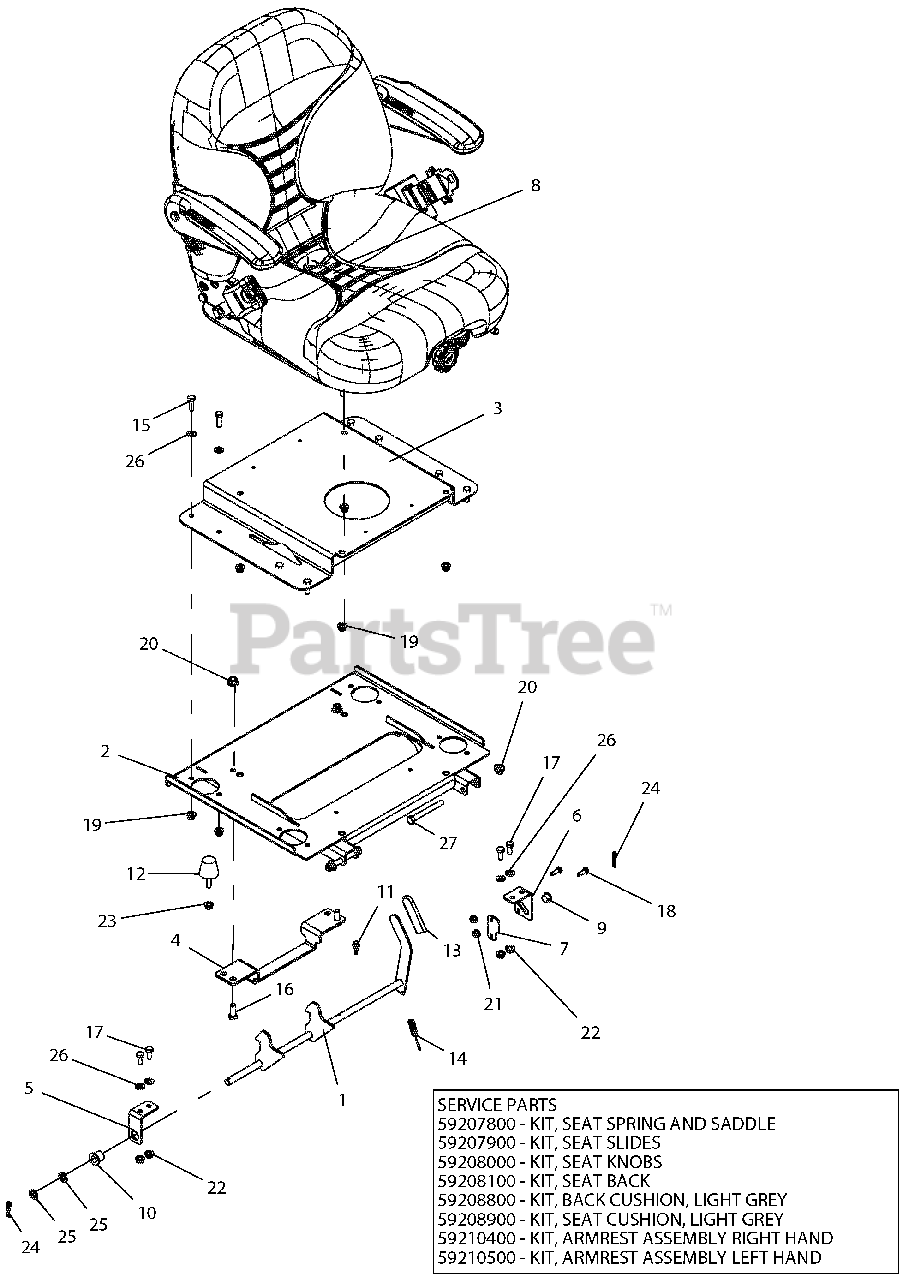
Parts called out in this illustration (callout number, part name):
1	WMT, SEAT LATCH
2	WLDMT, SEAT ISO MOUNTING-RED
3	WLDMT, SEAT BASE MOUNTING-RED
4	BRKT, SEAT LATCH-BLACK
5	MOUNT, SEAT LATCH - RH
6	MOUNT, SEAT LATCH - LH
7	RETAINER-SEAT LATCH
8	SEAT, SUSPENSION W/SEAT BELT, LT GRAY
9	BUSHING, POLYLINER - .50 SPLIT
10	BSHG, FLANGE .515 X .750 X .745 X 1.00 NYLON
11	CABLE TIE W/ TREE (.25 HOLE)
12	BUMPER, STUD MOUNTED CONE SHAPED
13	GRIP-VINYL-YELLOW .125 x 1.0 x 3.0
14	SPRG, EXTENSION
15	BLT-HEX .31-18X1.00 GR5 YWZC
16	BLT-HEX .38-16X1.00 GR5 YWZC
17	BLT-HEX .31-18X.75 GR5 YWZC
18	BLT-HEX .25-20X.75 GR5 YWZC
19	NUT-LK-NYL-FLG .31-18 YWZC
20	NUT-LK-NYL-FLG .38-16 YWZC
21	NUT, LK-TOP-FLG .25-20 YWZC
22	NUT, LK-TOP-FLG .312-18 YWZC
23	@NUT-SPNLK-FLG .312-18 YWZC
24	PIN-HAIR INT .08X.38X1.42 YWZC
25	WSHR-FL-STL .520X.827X.062 YWZC
26	WSHR-FL-STL.344X.688X.065YWZC
27	BLT-HEX .38-16X3.25 GR5 YWZC
